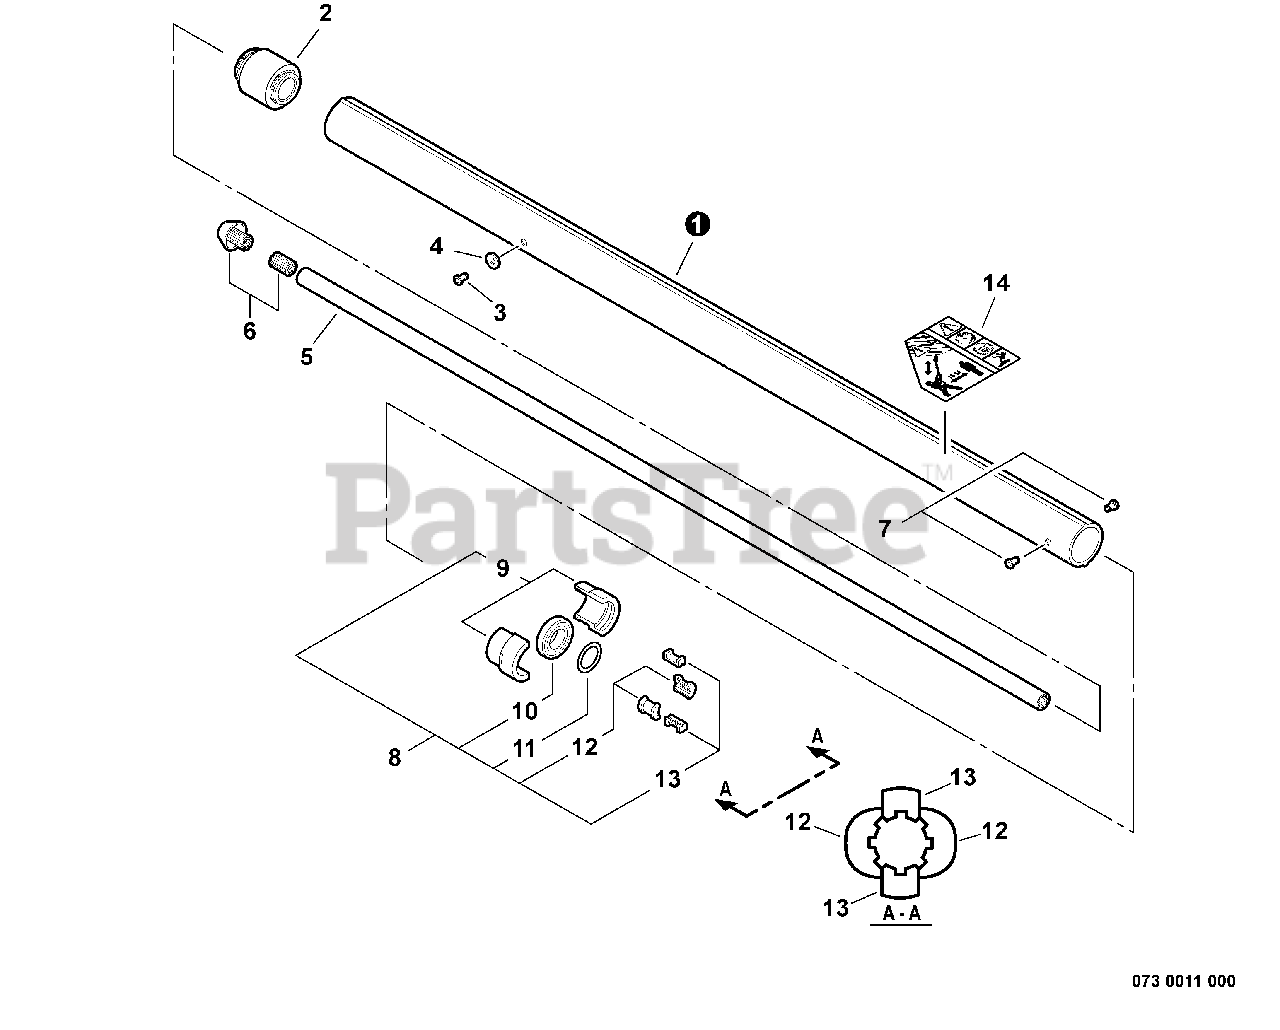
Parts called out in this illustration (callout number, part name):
1	PIPE, UPPER L= 80
2	GUIDE, SHAFT
4	WASHER, FLAT 5
5	SHAFT, UPPER DRIVE L= 79.75
6	ADAPTER, UPPER DRIVE SHAFT
8	HOLDER ASSY, BEARING
9	HOLDER, BEARING
10	BEARING, BALL 6002 DDU
11	WASHER, WAVE
12	GUIDE, SHAFT - LARGE
13	GUIDE, SHAFT - SMALL
14	LABEL, CAUTION - ELECTRICAL
